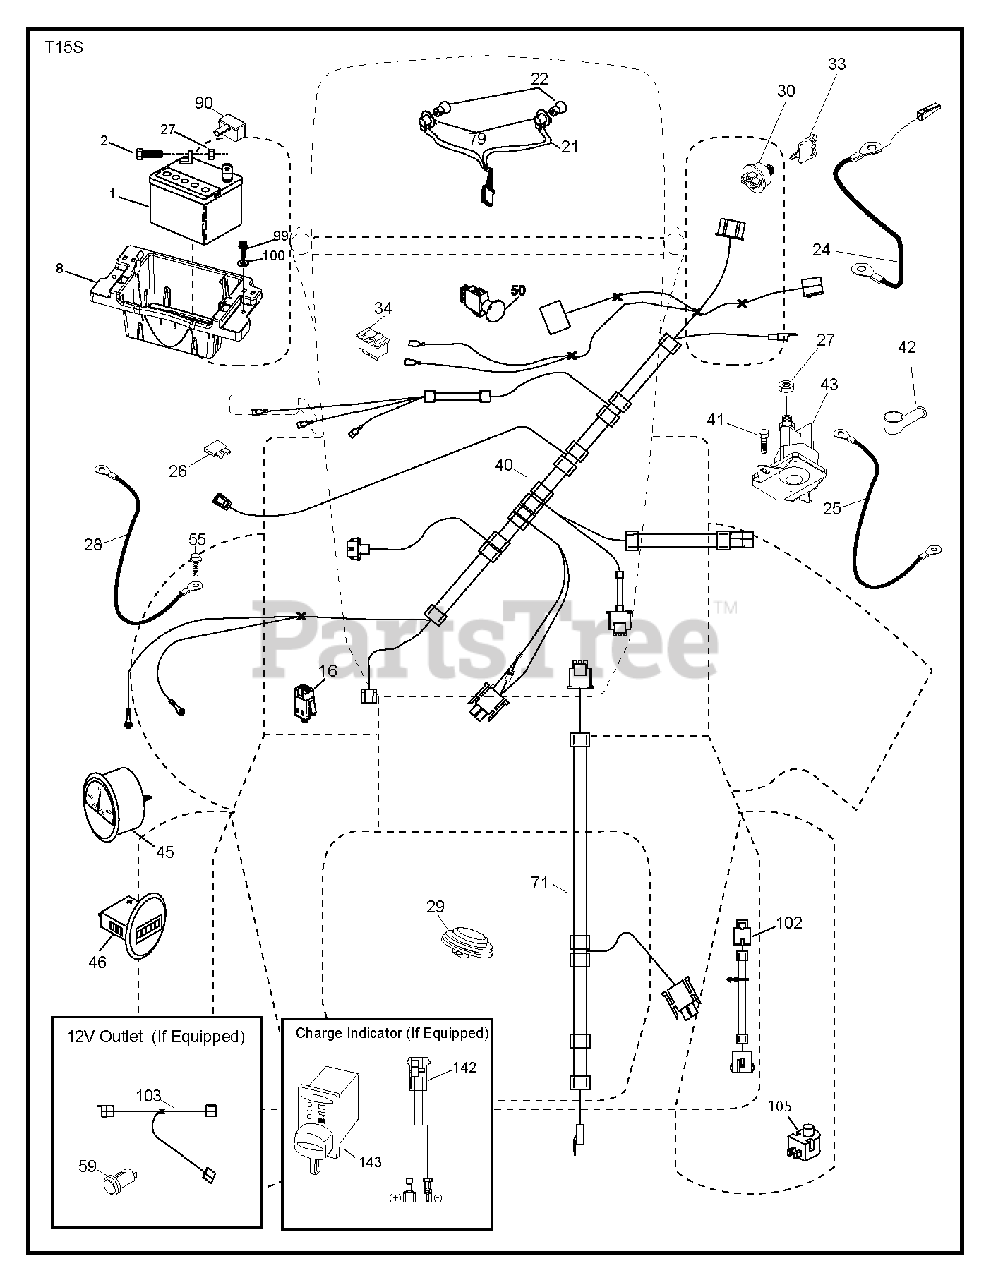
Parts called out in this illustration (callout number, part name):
1	Battery, Dry 30 Amp
2	BOLT.HEX.1/4.X.3/4.DICHROMATE
8	TRAY.BATTERY BOX.FRONT
16	SWITCH INTERLOOK PUSH-IN
21	HARNESS.LIGHT W/4152J BULBS
24	CABLE.FRBATT.W/WIRE.8GA.8
25	CABLE.STARTER.8GA.17.5
26	FUSE 20AMP
27	NUT
28	CABLE.GROUND.21"BLK.8GA.90T
29	SWITCH.SEAT.DELTA.OPC.
30	SWITCH.IGN.DELTA.W.LGH.ROS
33	KEY.CHAIN.BLISTER.PACK.GEN.INT
40	HARNESS IGN. DASH
41	SCREW
42	TERMINAL COVER
43	SOLENOID.W/BRASS.PLUNGER
45	GAUGE.AMMETER.SILVER/WHITE
46	GAUGE.HOUR.METER.SILVER/WHITE
50	RB PTO.SWITCH.8 TERMINAL.BLACK
55	SCREW 5/16"
59	OUTLET.12-VOLT
71	HARNESS-CHASSIS SUB
79	BULB HOLDER ASM.
90	COVER.TERMINAL.BATTERY
99	SCREW HEXWSHR 1/4-20X3/4
102	HARNESS PIGTAIL PCH TEX ROS
103	HARNESS.PIGTAIL.12V.OUTLET.
105	REVERSE SWITCH
